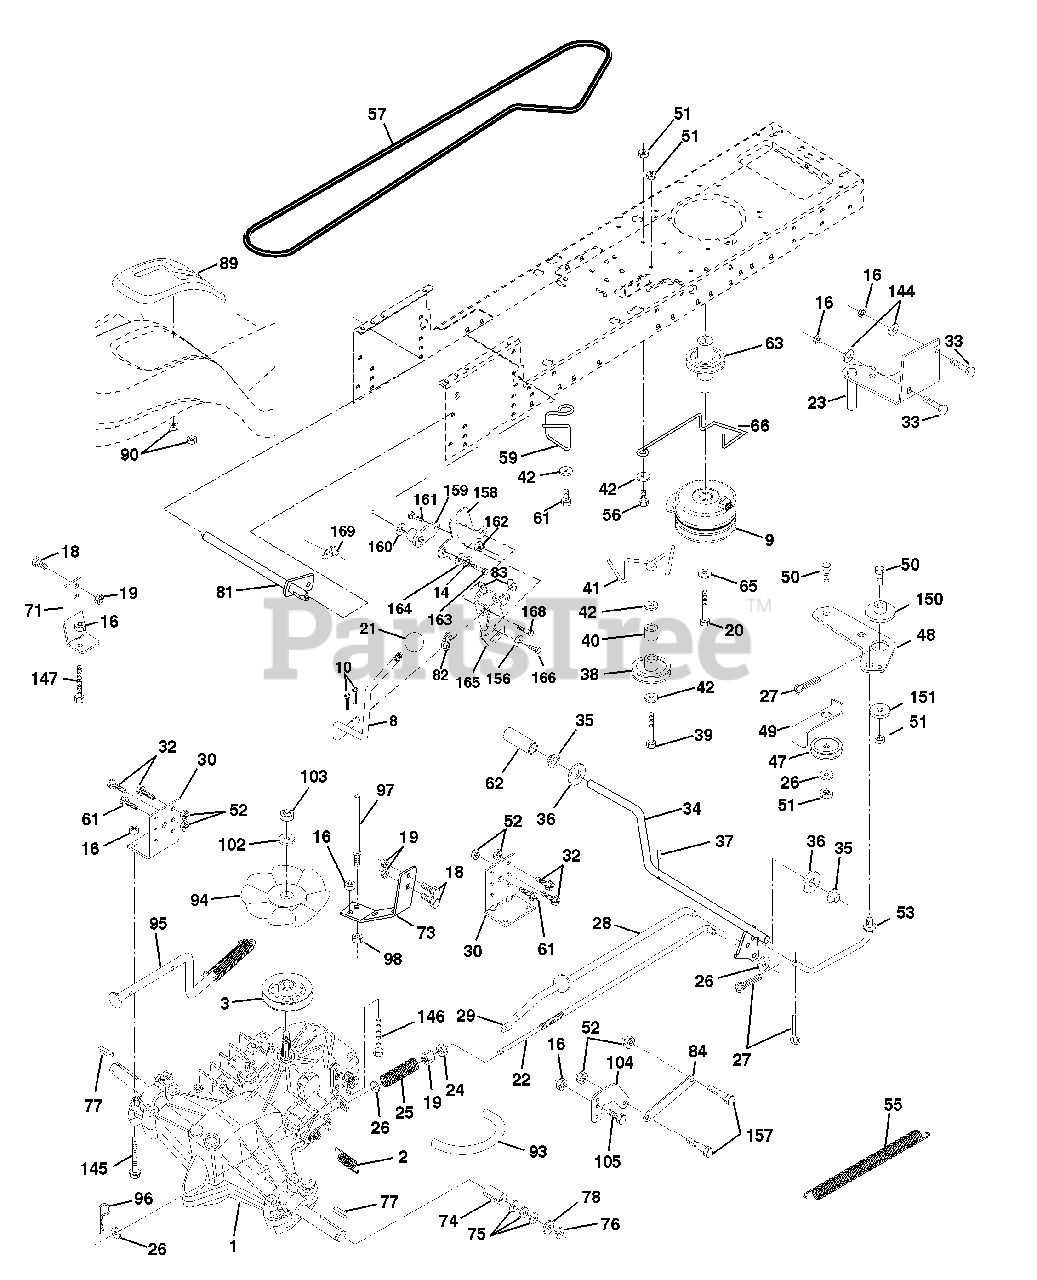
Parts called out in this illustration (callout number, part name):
1	Transaxle w/cas Hydro 319-0650
2	Spring, Return, Brake
3	Pulley, Transaxle Hydro 750 LT
8	Rod Shift STLT
9	Clutch Electric
10	Pin Cotter 1/8 x 1 CAD
16	Nut Lock Hex W/Ins. 5/16-18 Unc P
17	Washer 1-1/2 OD x 15/32 ID x .250
18	Bolt Fin Hex 3/8-16 Unc x 1 Gr.5
19	Nut Lock Hex W/Ins 3/8-16 Unc
20	Bolt, Hex 7/16-20 x 4-1/4 Ga. 5
21	Knob Deluxe 1/2-13 UNC BLK/BLK
22	Rod, Brake Hydro
23	Bracket Asm Mtg CL
24	Nut Hex Jam 3/8-16 UNC
25	Spring, Brake Rod
26	Washer
27	Pin Cotter 1/8 x 3/4 CAD.
28	Rod, Parking Brake
29	Cap,Parking Brake
30	Bracket, Transaxle
32	Bolt Hex Hd 5/16-18 Unc x 3/4
33	Bolt Carriage 5/16-18 UNC x 3/4
34	Shaft, Foot Pedal
35	Bearing, Nylon
36	Washer
37	Pin, Roll
38	Pulley, Idler, Flat
40	Spacer Split
41	Keeper, Belt Idler
42	Washer 13/32 x 13/16 x 12 Ga
47	Pulley, Idler, V-Groove Plastic
48	Bellcrank Clutch Grnd Drv STL
49	Retainer, Belt Style Spring
50	Bolt
52	Nut Crown Lock 5/16-18
53	Link, Clutch
55	Spring, Return, Clutch
56	Bolt, Fin Hex 3/8-16 UNC x 1 1/4
57	V-Belt, Ground Drive
59	Keeper, Center Span
61	Screw Thdrol. 3/8-16 x 3/4 Ty. TT
62	Cover, Pedal Premium
63	Pulley, Engine
65	Washer Lock Hvy HLCL Spr 7/16
66	Keeper Belt Engine
71	Strap Torque Lh Hydro 18/20" T
73	Strap Torque Rh Hydro 0650
74	Spacer, Split
75	Washer 25/32 x 1-1/4 x 16 Ga.
77	Key, Square
78	Washer 25/32 x 1-5/8 x 16 Ga
81	Shaft Asm. Cross Hydro 20" Tires
82	Spring Torsion T/A
83	Washer 17/32 x 3/4 x 16 Ga.
84	Rod, Tie 20" Tires
87	Washer 21/32 x 1-1/4 x 16 Ga.
88	Ring Klip #5304-62
89	Console, Shift Hydro STLT
90	Nut Self-Thd Wsh-Hd 1/4 Zinc
93	Line Fuel Hydro 4"
94	Fan, Hydro 7"
95	Control Asm. Bypass Hydro
96	Retainer Spring 1" Zinc/Cad
97	Keeper Belt Rh Hydro 0750.18/20"
98	Nut Keps Hex 3/8-16 Unc
100	Washer 11/32 x 3/4 x 16 Ga.
102	Washer Belleville .501D x 1.50D
103	Nut Hex Jam Toplock 1/4-20 Unf
104	Arm, Control Hydro
105	Screw Cap Hex 5/16 x 18 x 1
106	Bolt Fin Hex 5/16-18 Unc x 1-1/4
144	Washer 11/32 x 5/8 x 16 Ga.
145	Bolt Hex 5/16-18 Unc Flghd
146	Bolt Hex Flghd 5/16-18 x 2-1/4
147	Bolt Hex Flghd 5/16-18 x 1-1/2
149	Spacer Retainer PM Mower
150	Bushing Nylon Collered
151	Washer 13/32 x 2 x 10 Ga.
